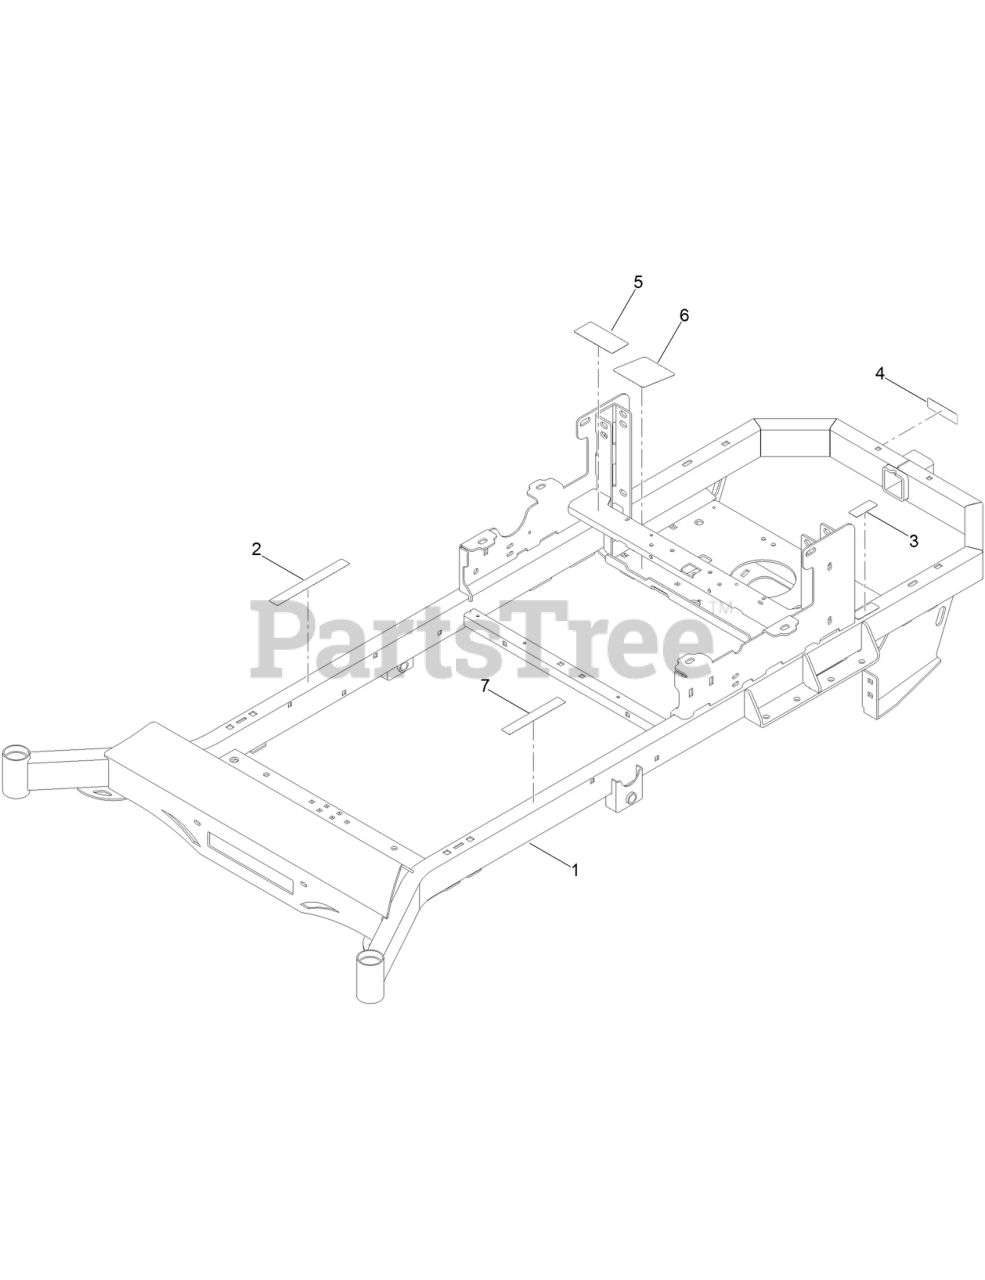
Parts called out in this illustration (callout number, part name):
1	ZTR FRAME ASM
2	DECAL-WARNING
3	DECAL-HOT SURFACE
4	DECAL-HITCH
5	DECAL-ROTATING FAN HAZARD
6	DECAL-PUMP BELT ROUTING-PARKER
7	DECAL-WARNING
